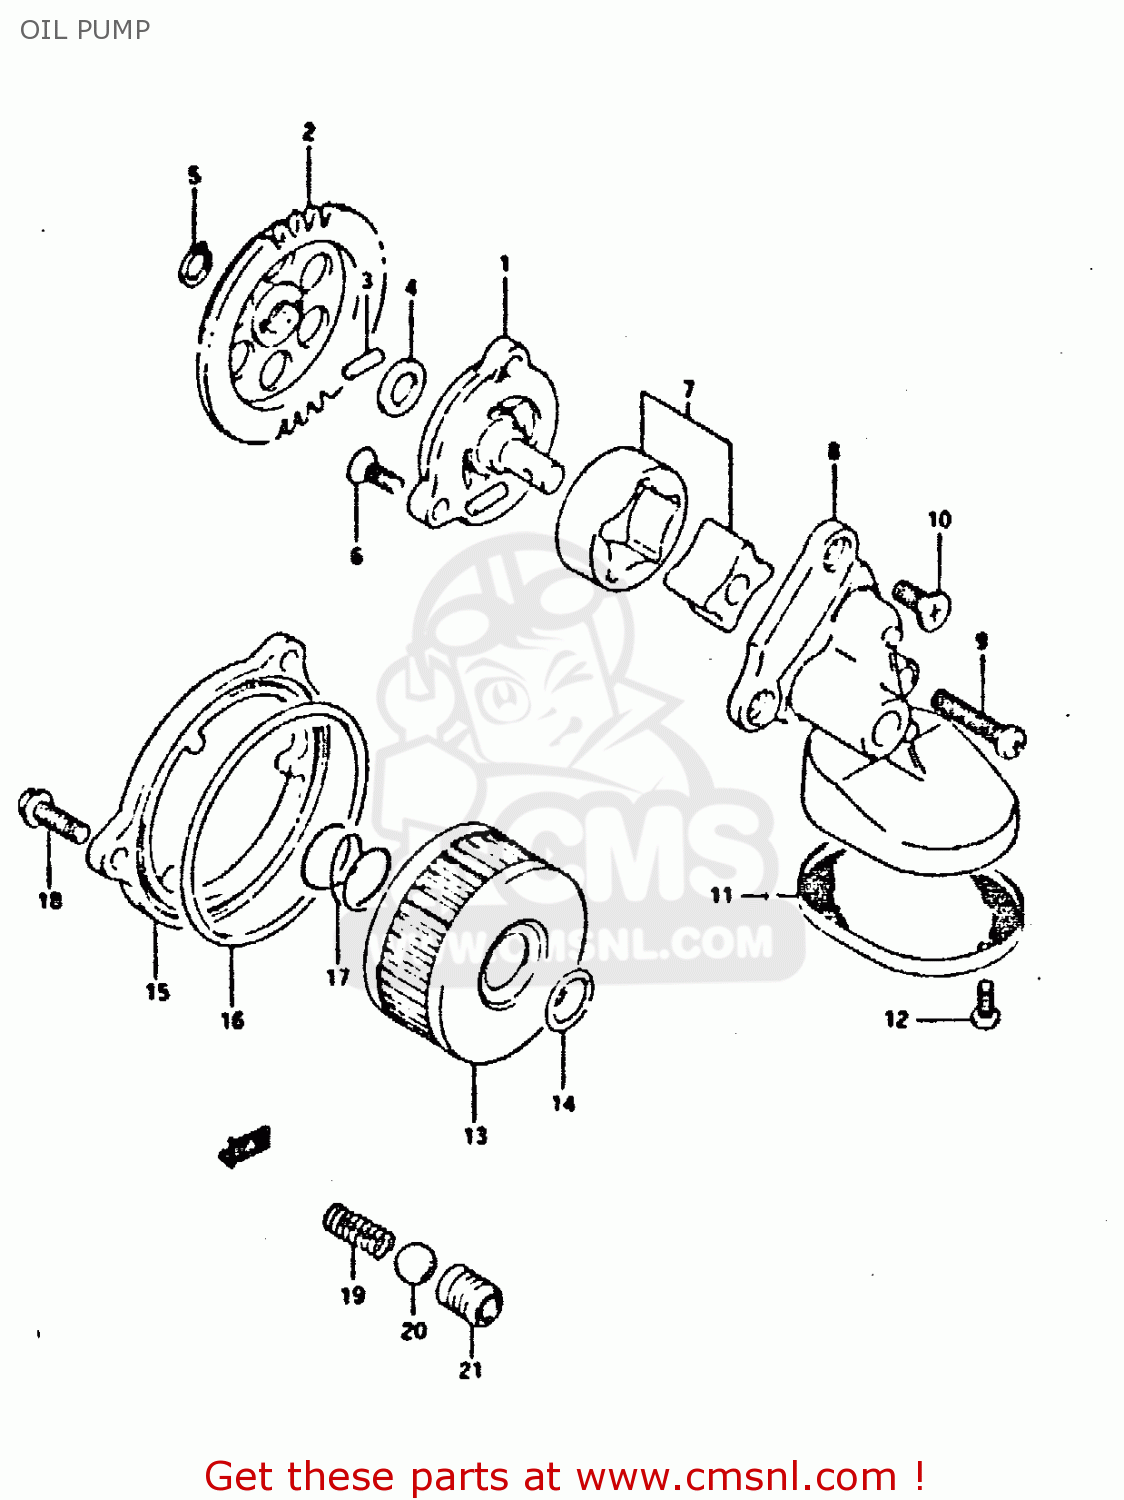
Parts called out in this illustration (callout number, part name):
1	PUMP ASSY,ENGINE OIL NO.1
2	GEAR,OIL PUMP DRIVEN (N
3	PIN(4X15.8)
4	SHIM
5	CIRCLIP,10MM
6	SCREW ,6X16
7	ROTOR SET,OIL PUMP,NO.2
8	COVER,OIL PUMP NO.2
9	SCREW,6X30
10	SCREW ,6X16
11	STRAINER,OIL PUMP NO.2
12	SCREW
13	FILTER ASSY,ENGINE OIL
14	O RING(D:2.4,ID:15.8)
15	CAP,OIL FILTER
16	O RING(D:2.4,ID:73)
17	SPRING
18	BOLT
19	SPRING
20	BALL
21	SEAT,OIL CHECK VALVE
